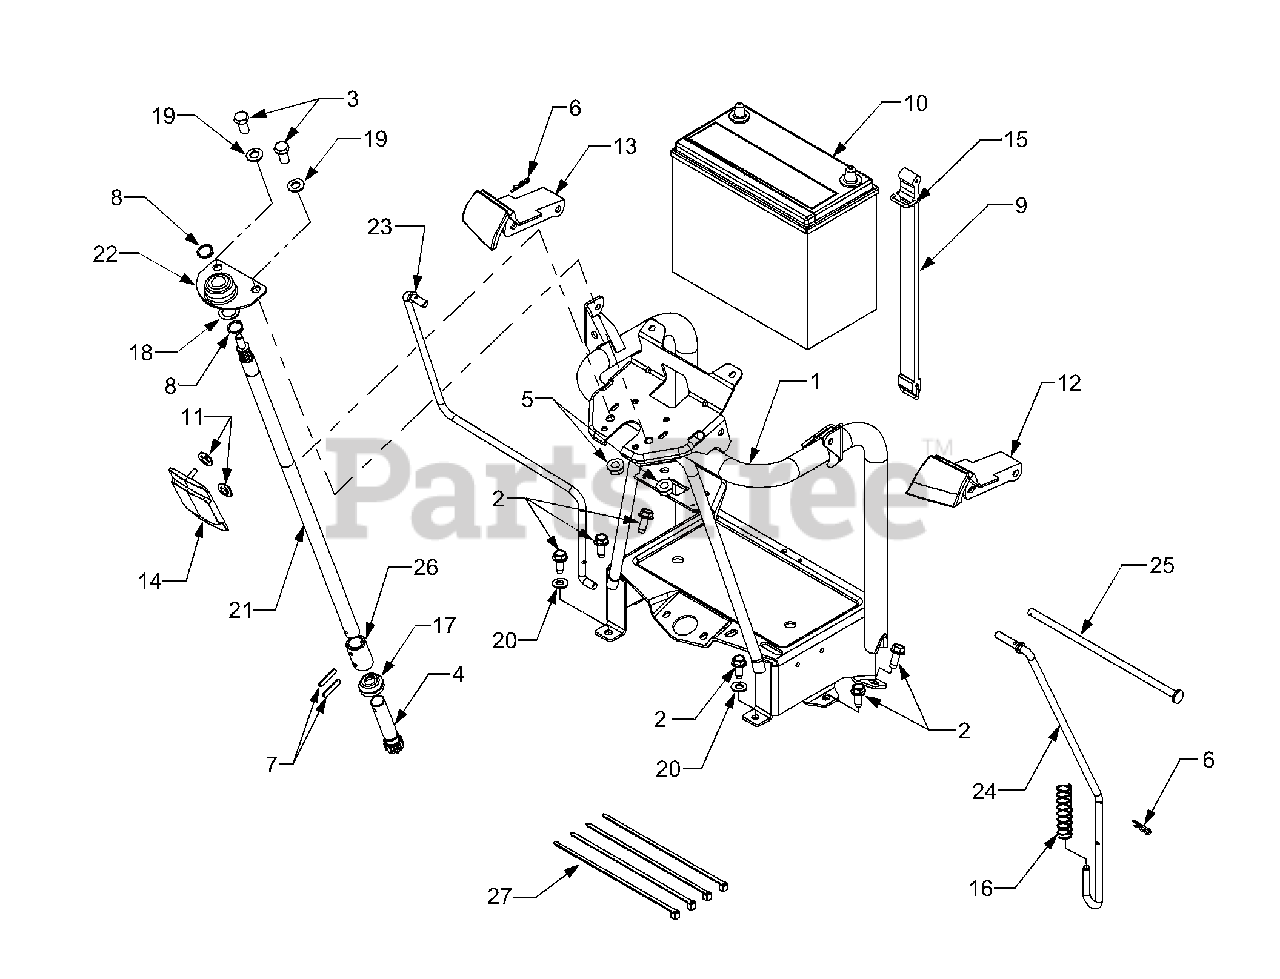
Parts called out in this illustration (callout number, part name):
1	Pedestal Assembly
2	Screw, Hex Wash. Hd. Tapp 5/16-18 x .75
3	Screw, Hex Cap 3/8-16 x .75 GR5
4	Shaft, Lower Steering
5	Nut, Hex Flange Lock, 3/8-16
6	Pin, Internal Cotter
7	Pin, Spirol, 3/16 x 1.0
8	Ring, Retaining, .56 Dia Shaft
9	Strap, Battery
10	Battery
11	Push Nut, .188 Dia.
12	Lever, Park Brake
13	Lever, Cruise
14	Cover, Fixed Steering
15	Hook, Wire Rectangular
16	Spring, Compression, .676 x 2.57
17	Boot, Shaft Cover
18	Washer, Flat, .635 x .93 x .06
19	Washer, Flat, .375 x .738 x .063
20	Washer, Flat, .344 x .688 x .065
21	Shaft, Upper Steering
22	Bearing, Steering Support
23	Rod, Cruise Control
24	Rod, Parking Brake
25	Rod, Cruise/Brake Pivot
26	Sleeve, Fixed Steering
27	Cable Tie, Harness
